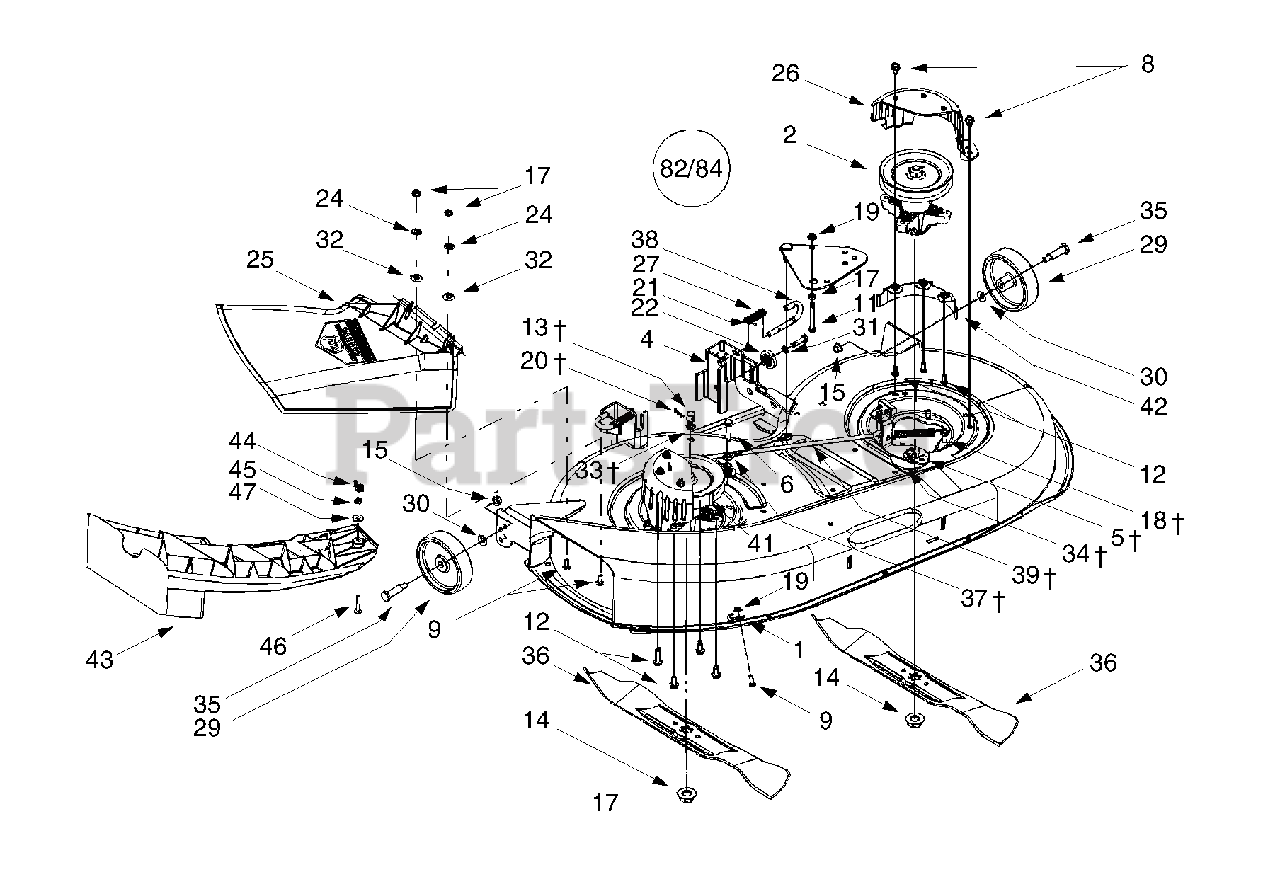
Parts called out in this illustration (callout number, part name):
1	Retainer Hook
2	Spindle Assembly, 5.75 Dia.
5	Deck Brake Assembly, 42-inch Decks
6	Hex Cap Screw, 3/8-16 x 1.5
8	Self-tapping Screw, 5/16-18 x .625
9	Hex Cap Screw, 1/4-20 x .62
12	Self-tapping Screw, 5/16-18 x .75
13	Ferrule, 5/16-18
14	Hex Flange Nut, 5/8-18
15	Flange Lock Nut, 3/8-16
17	Hex Nut, 1/4-20
18	Hex Lock Nut, 5/16-18
19	Hex Flange Lock Nut, 1/4-20
20	Internal Cotter Pin, .072 x 1.12
21	Cotter Pin, 3/32 x 1.0
22	Deck Adjustment Gear
24	Push Nut. .25 x .5
25	Side Discharge Chute Assembly
26	Belt Cover
27	Compression Spring, .406 x .531 x 1.75
29	Deck Wheel, 5 x 1.38
30	Bell Washer, .401 x .87 x .063
31	Lock Washer, 5/16
32	Bell Washer, .265 x .75 x .062
33	Flat Washer, .344 x .688 x .065
34	Flat Washer, .320 x 3.0 x .125
35	Shoulder Screw, .498 x 1.53
36	Three-in-one Blade, Star Center, 21.23"
37	Bracket Cable, 5.35"
38	Deck Release Pin
39	Deck Brake Rod
43	Mulch Plug, 42-inch Decks
44	Wing Nut, 1/4-20
45	Hex Nut, 1/4-20
46	Hex Cap Screw, 1/4-20 x 1.0
47	Flat Washer, .28 x .74 x .063
